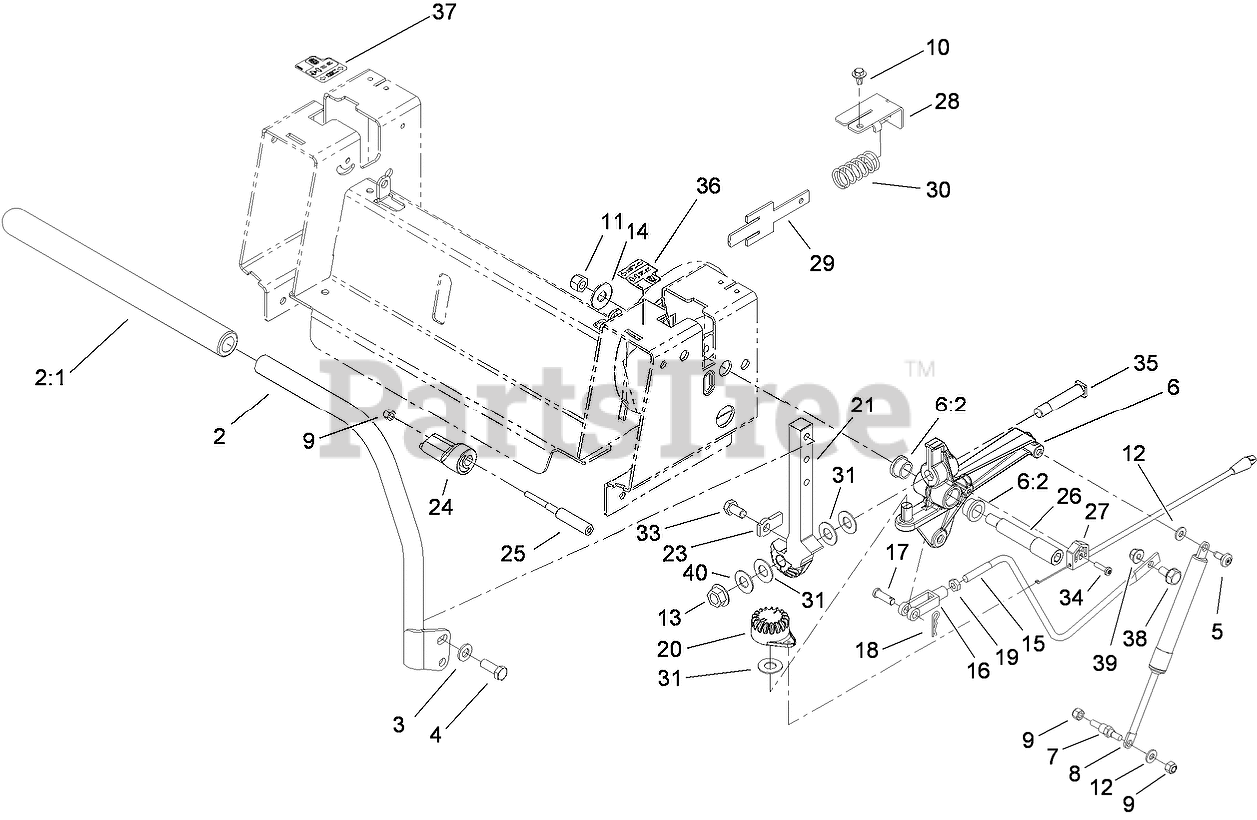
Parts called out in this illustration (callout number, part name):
2	LH HANDLE ASM
3	WASHER-FLAT
4	SCREW-HH
5	SCREW-SHOULDER
6	ACTIVATOR ARM ASM
6:2	BUSHING
7	STUD-DAMPER
8	Damper-Control, Motion
9	NUT-LOCK, NI
10	SCREW-HHFTF
11	NUT-LOCK, NI
12	WASHER-FLAT
13	NUT-HF
14	WASHER-FLAT
15	LINK-HYDRO
16	YOKE-ADJUSTABLE
17	PIN-CLEVIS
18	PIN-COTTER
19	NUT-JAM
20	GEAR-CONTROL
21	ARM-ACTUATOR, LH
23	TAB-STOP
24	ECCENTRIC
25	SCREW-ECCENTRIC
26	BOLT-SHOULDER
27	CABLE-BRAKE, PARKING
28	BRACKET-RETURN
29	PLATE-RETURN
30	SPRING-COMPRESSION
31	WASHER-PIVOT
33	SCREW-HH
34	SCREW-TORX
35	BOLT-SHOULDER
36	DECAL-CONTROL LEVER, LH
37	DECAL-CONTROL LEVER, RH
38	BOLT-SHOULDER
39	NUT-HF, NI
40	WASHER-TEFLON
